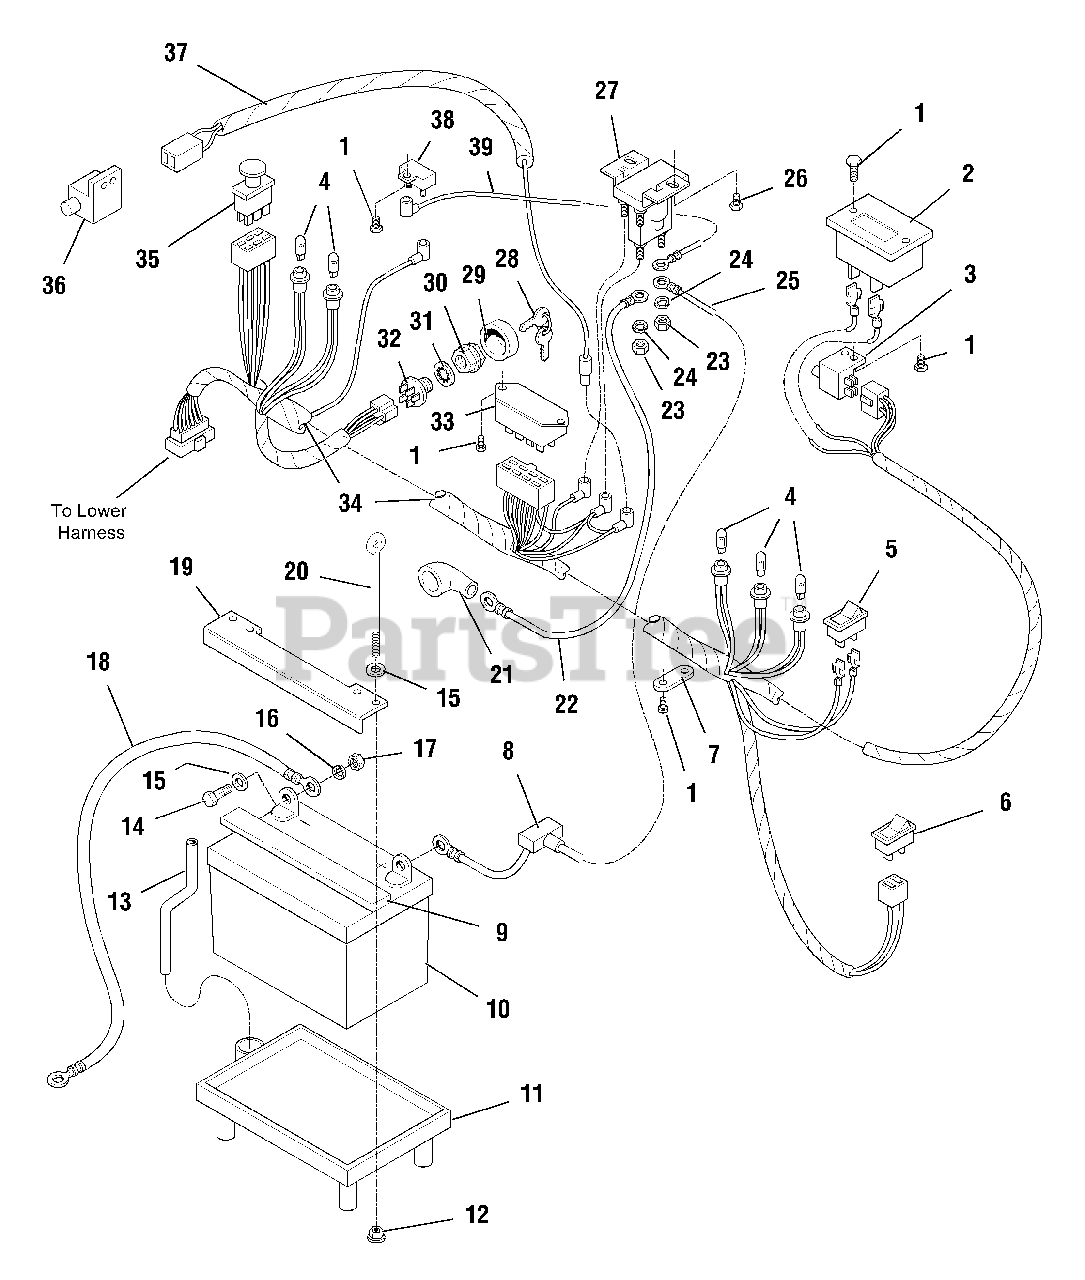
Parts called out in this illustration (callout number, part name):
1	SCREW, Plastite, #8-16 x 1/2
3	SWITCH, Transmission, Neutral Start
4	BULB, Indicator Light
5	SWITCH, Headlight
6	SWITCH, Lift
7	STRAP, Wire Retainer
8	BOOT, Insulator
9	VENT, Battery
10	BATTERY, 39 Amp (Power Max)
11	TRAY, Battery
12	NUT, Plastic, 1/4-20
13	HOSE, Battery, Drain
14	CAPSCREW, Hex, 1/4-20 x 3/4
15	WASHER, Plain, 9/32
16	LOCKWASHER, 1/4
17	NUT, Hex, Full, 1/4-20
18	CABLE, Battery-to-Ground
19	HOLD DOWN, Battery
20	ROD, Battery Hold Down
21	COVER, Terminal
22	CABLE, Solenoid-to-Starter
23	NUT, Hex, 5/16-24
24	LOCKWASHER, 5/16
25	CABLE, Battery-to-Solenoid
26	SCREW, Plastite, 1/4-20 x 5/8
27	SOLENOID
28	KEY, Ignition
29	COVER, Key Switch
30	ADAPTER, Nut
31	LOCKWASHER, Internal Tooth
32	IGNITION SWITCH
34	HARNESS, Upper
35	SWITCH, PTO, Electric Clutch
36	SWITCH
37	HARNESS, Wiring
38	CIRCUIT BREAKER
